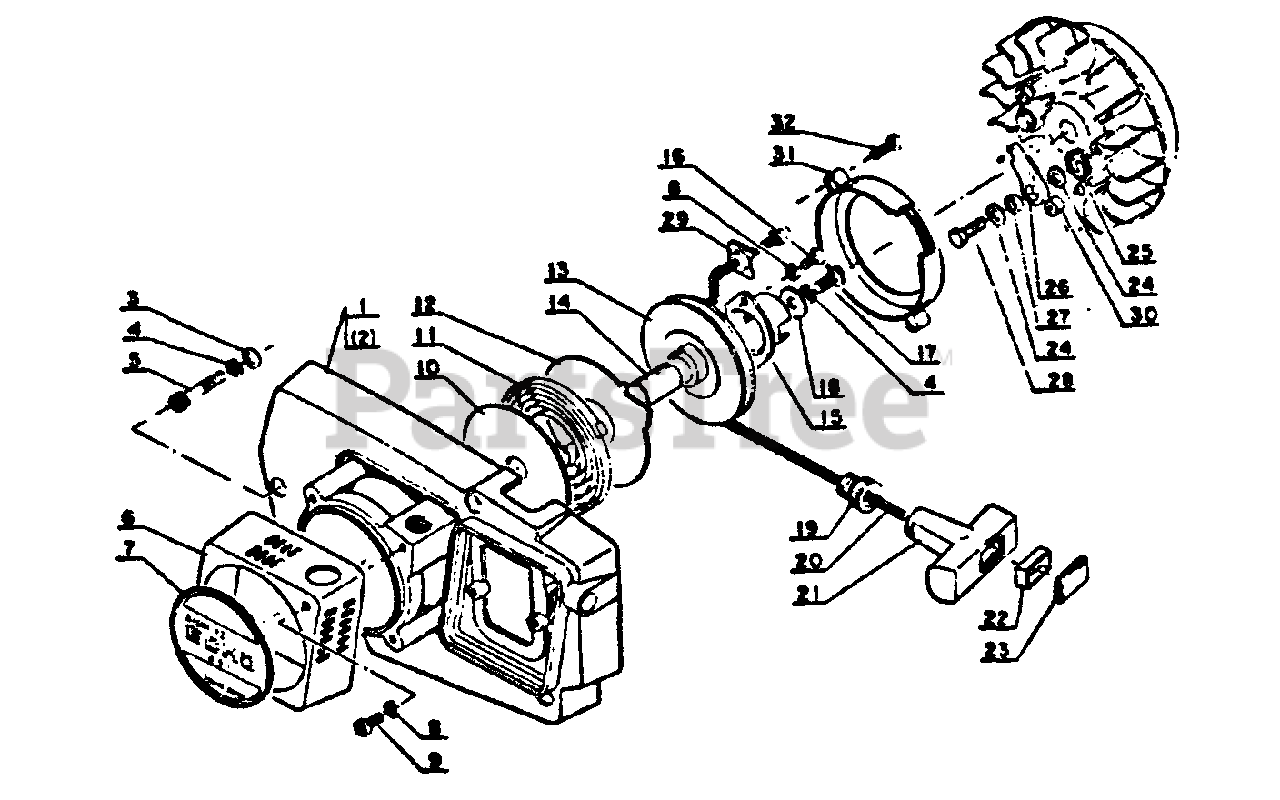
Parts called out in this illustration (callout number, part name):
1	CASE, STARTER
3	WASHER - 5
4	LOCKWASHER - 5
5	BOLT - 5X25
6	FILTER, DEBRIS
7	NAME PLATE
8	LOCKWASHER - 4
9	SCREW - 4X8
10	PLATE, STARTER
11	SPRING, REWIND
12	PLATE, STARTER
13	REEL, ROPE
15	CATCHER, PAWL
16	SCREW - 4X10
17	BOLT - 5X12
18	WASHER - 5
19	GUIDE, ROPE
20	ROPE, STARTER - 4X950
21	GRIP, STARTER
22	RING, RETAINING
24	WASHER - 5
25	SPRING, RETURN
26	PAWL, STARTER
28	BOLT - 5X18
29	RETAINER, ROPE
31	COVER, DUST
32	SCREW - 4X16
